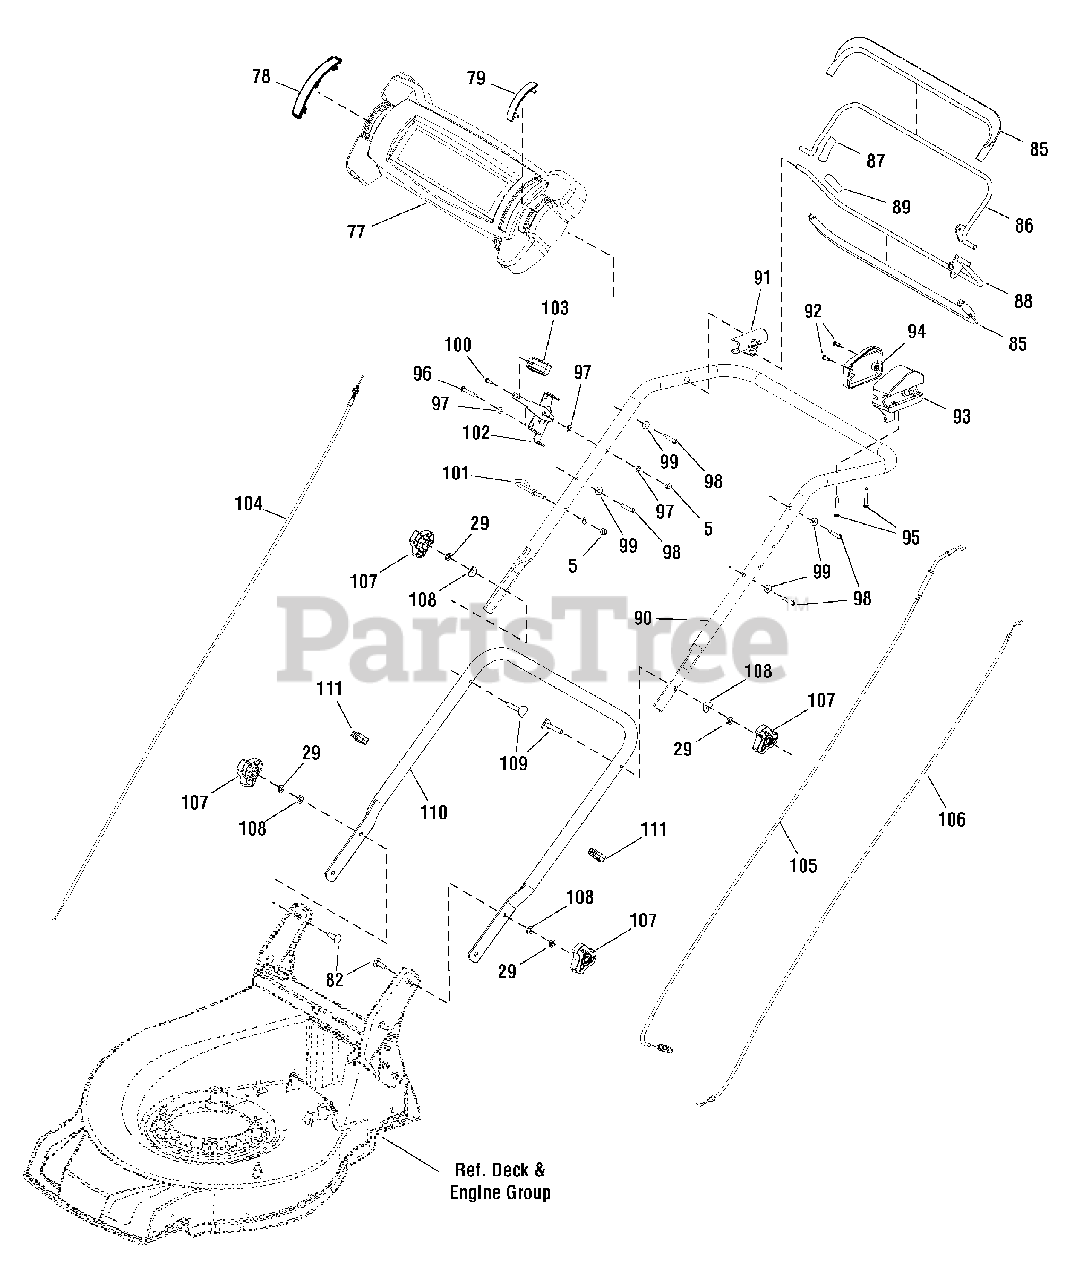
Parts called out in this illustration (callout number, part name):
5	NUT, Hex, Nylon Insert, Torque Type
29	WASHER, Spring
77	PANEL, Handle Cover
78	INSERT, Throttle Cover
79	INSERT, Throttle Cover
82	BOLT, Carriage
85	COVER, Handle
86	LEVER, Brake
87	COVER, Brake
88	LEVER, Clutch
89	COVER, Clutch
90	HANDLE, Upper
91	hinge
92	SCREW, Pan Head, Cross Recessed Tapping
93	CABLE BOX, Control Lever
94	COVER, Control Lever Cable Box
95	SCREW, Pan Head, Cross Recessed Tapping
96	SCREW, Pan Head, Cross Recessed, H-Form
97	WASHER, Flat, C Class
98	SCREW, Pan Head, Cross Recessed Tapping
99	WASHER, Large, A-Class
100	SCREW, Pan Head, Cross Recessed Tapping
101	HOOK, Start Rope
102	FRAME, Throttle
103	GRIP, Throttle
104	CABLE, Throttle
105	CABLE, Clutch
106	CABLE, Brake
107	KNOB, Lock
108	WASHER, Curved
109	BOLT, Connecting
110	HANDLE, Lower
111	CLIP, Cable
